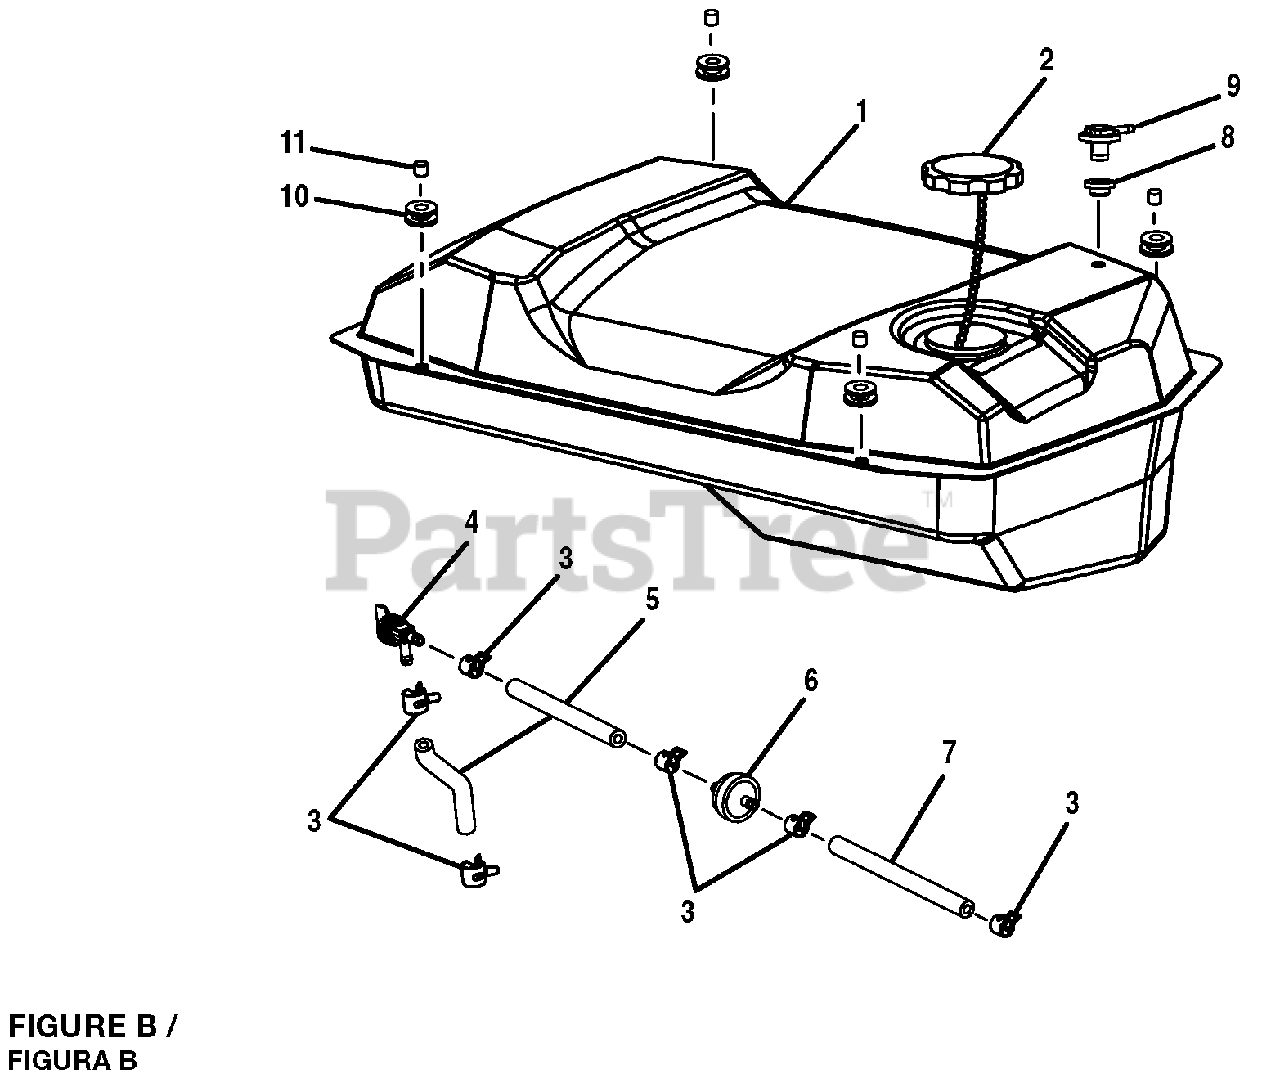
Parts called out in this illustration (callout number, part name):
1	Fuel Tank
2	Fuel Tank Cap
3	Fuel Line Clamp (1/2 in.)
4	Fuel Shut Off Valve
5	Fuel Line (6.4 mm x 72 mm
6	Fuel Filter
7	Fuel Line (6.4 mm x 144 mm)
9	Rollover Valve
10	Bushing (Fuel Tank Isolator)
11	Spacer (Fuel Tank Isolator)
